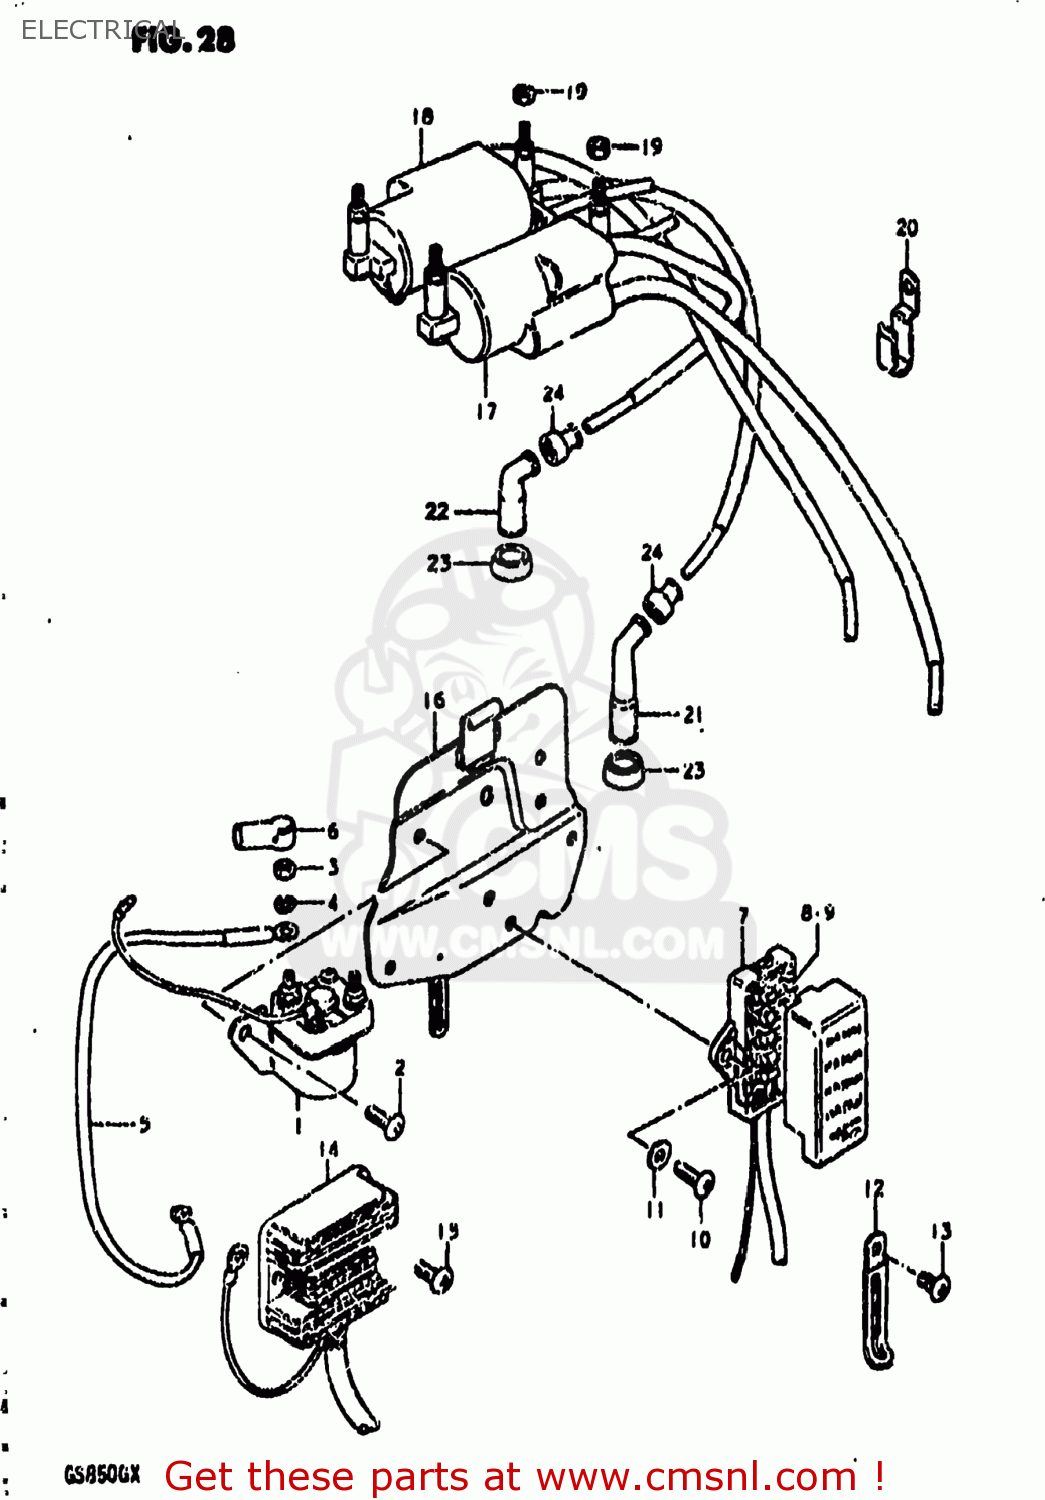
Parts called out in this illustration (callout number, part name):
1	RELAY ASSY,STARTING MOTOR
2	SCREW
3	NUT 6MM
4	LOCK WASHER
5	WIRE,STARTER MOTOR LEAD
6	CAP,STARTER RELAY
7	BOX ASSEMBLY,FUSE
8	FUSE(10A)
9	FUSE(15A)
10	SCREW 6X12
11	WASHER
12	CLAMP L:35
13	SCREW
14	RECTIFIER ASSEMBLY
15	SCREW 6X12
16	HOLDER COMP,ELECTRONIC PARTS
17	COIL ASSEMBLY,IGNITION
18	COIL ASSEMBLY,IGNITION
19	NUT
20	CLAMP
21	CAP ASSY,SPARK PLUG
22	CAP,SPARK PLUG
23	SEAL,SPARK PLUG
24	SEAL,SPARK PLU
